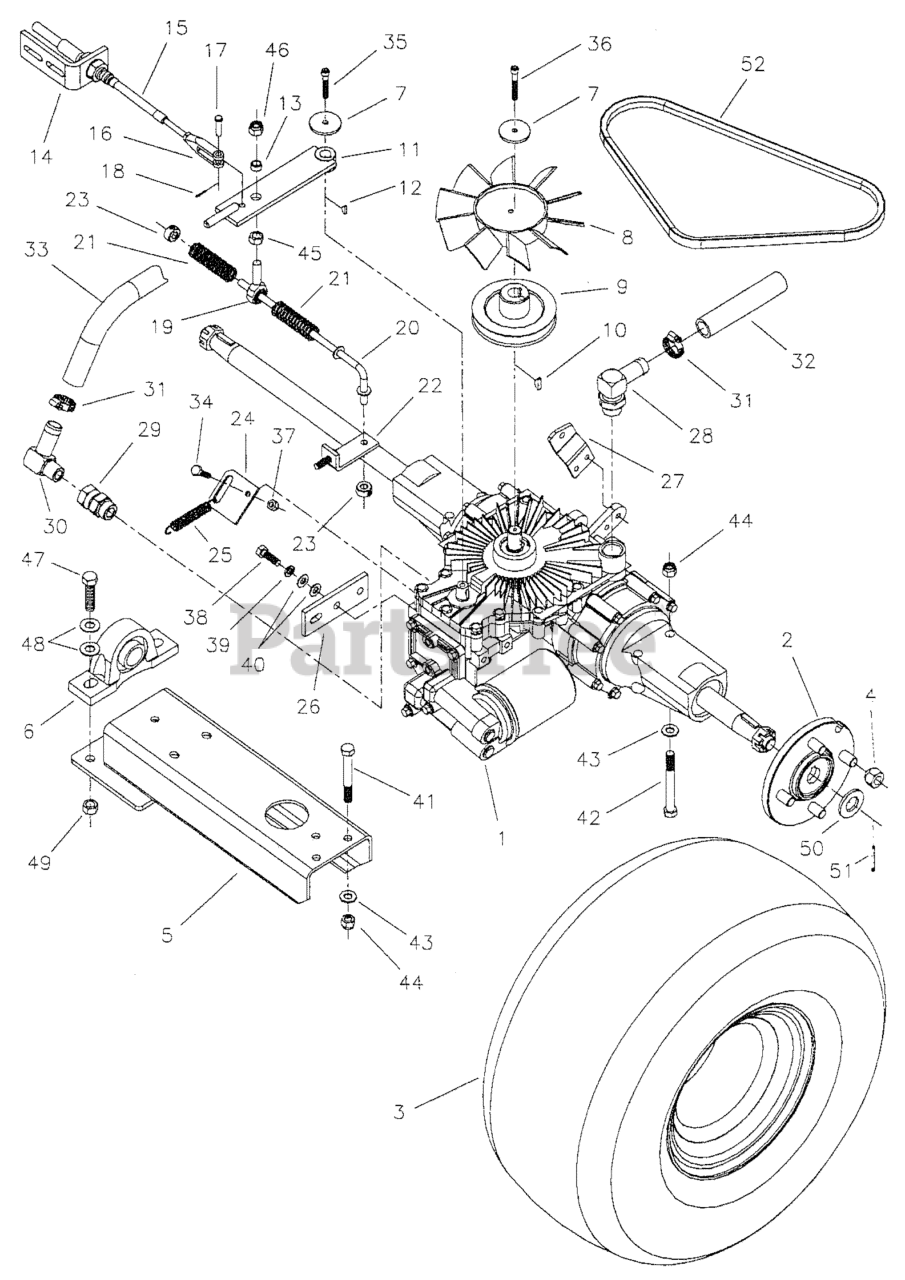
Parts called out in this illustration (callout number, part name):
1	Transmission
1	Oil Filter
1	Nut, Hex Slotted
1	Key, Woodruff
2	Hub, 4 Bolt Tapered
3	Tire, 20" Drive
4	Nut, Lug
5	Support, Axle
6	BEARING, PILLOW BLOCK, 1
7	Washer, Fan Retaining
9	Pulley, Transmission Input
10	Key, Hi-Pro Woodruff
11	Arm, Stroke
12	Key, Woodruff
13	Spacer
14	Bracket, Cable
15	Cable, Speed Control
17	Pin, Clevis
18	Pin, Cotter
19	Ball Joint, 3/8" Male
20	ROD, NEUTRAL SPRING WELDMENT
21	Spring, Compression
22	Bracket, Neutral
23	Collar, 5/16" Set
24	Lever, Dump Valve
25	Spring, Extension
26	Bracket, Transmission Support
27	Lever, Brake
28	Fitting, 90° 7/8" a-Ring
29	Fitting, Straight 7/8" a-Ring Swivel
30	Fitting, 90° 1/2'' NPT
31	Clamp, #10 Hose
32	Hose, Inlet
33	Hose, Return
34	BOLT, 1/4-20 X 1" GD5 CZ
35	Bolt, 1/4-20 x 1/2," Allen Head wi Patch
36	Bolt, 1/4-20 x 3/4" Allen Head wi Patch
37	NUT, 1/4-20 HEX NYLON LOCK
38	Bolt, 5/16-18 x 1" GD5
39	WASHER, 5/16 LOCK CZ
40	WASHER, 5/16" SAE
41	BOLT, 3/8-16 X 3" GD5 CZ
42	BOLT, 3/8-16 X 3-1/2" GD5 CZ
43	Washer, 3/8" GD.9
44	NUT, 3/8-16 HEX NYLON LOCK
45	Nut, 3/8-24 Hex
46	Nut, 3/8-24 Hex Nylon Lock
47	BOLT, 7/16-20 X 1-3/4" GD.5
48	Washer, 7/16" SAE
49	Nut, 7/16-20 Hex Nylon Lock
50	WASHER, 3/4 SAE
51	PIN, COTTER, 1/8 X 1-1/4
52	Belt, Hydro Drive
